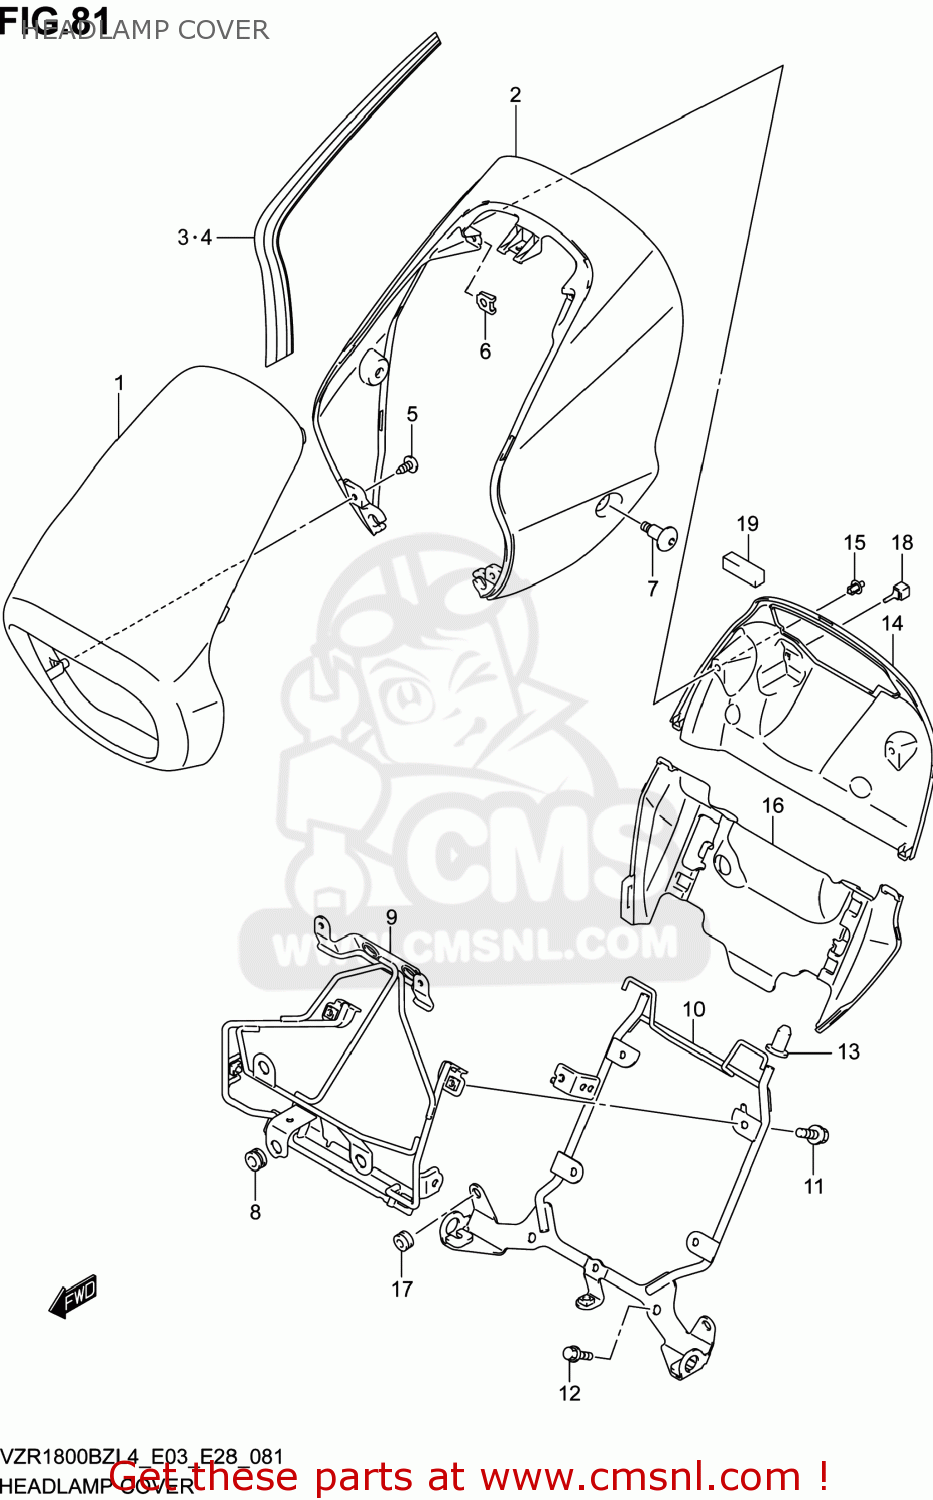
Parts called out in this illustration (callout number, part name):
1	COVER,HEADLAMP
2	COVER,HEADLAMP LOWER
3	TAPE,HEADLAMP HOUSING LOWER,R
4	TAPE,HEADLAMP HOUSING LOWER,L
5	SCREW
6	NUT
7	SCREW(6X22)
8	CUSHION
9	BRACE,HEADLAMP HOUSING
10	BRACE COMP,HEA
11	BOLT
12	BOLT
13	CUSHION,HEADLAMP HOUSING BRACE
14	COVER,HEADLAMP UPR
15	CLIP(BLACK)
16	COVER,HEADLAMP HSG BRACKET
17	CUSHION
18	CUSHION,HEADLAMP COVER UPR
19	CUSHION
